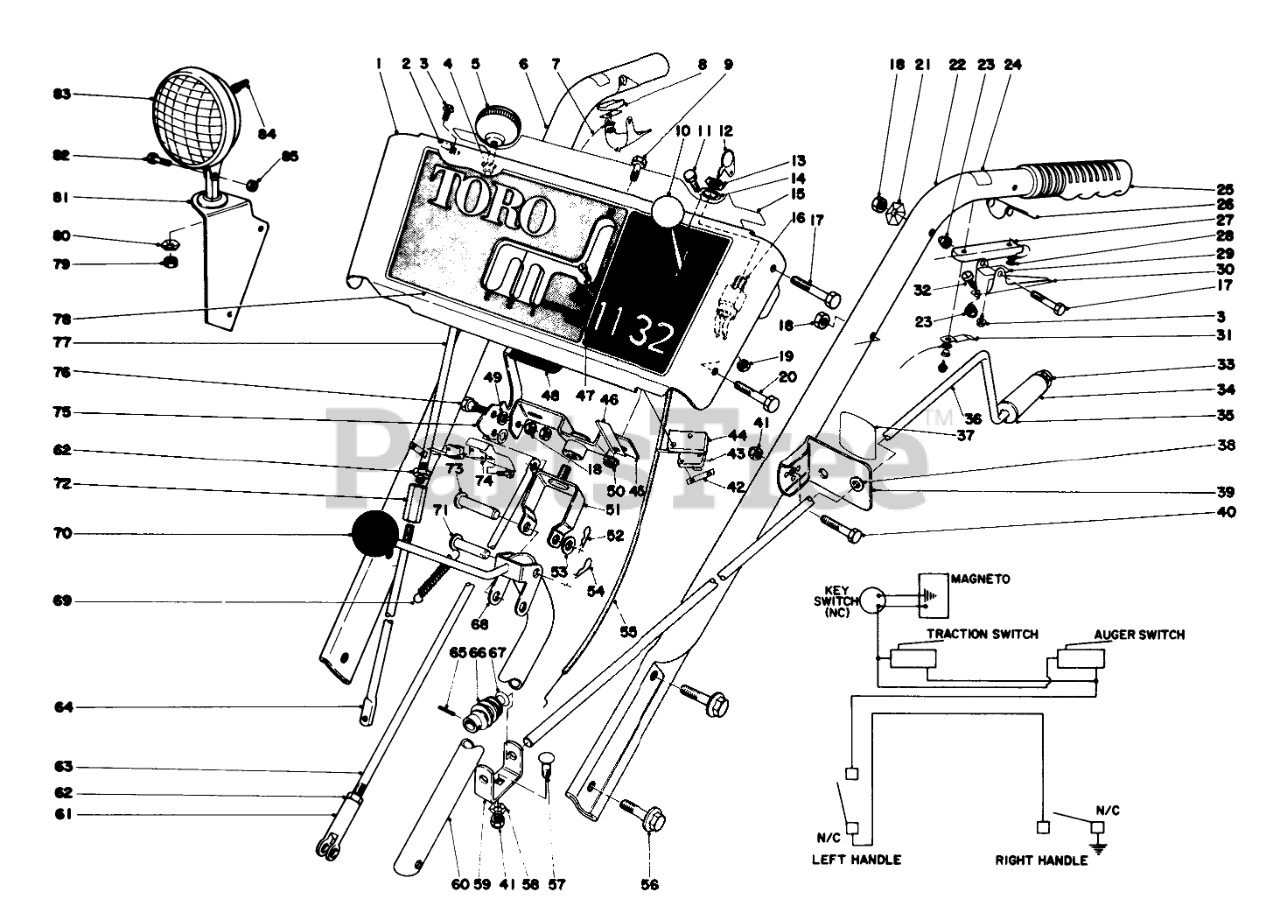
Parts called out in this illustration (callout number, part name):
1	Escutcheon Plate (Incl. Ref. #15 & 78)(Model 38160)
2	PLASTIC CLIP
3	SCREW
4	NYLINER #6LI-FF TYPE 7
5	KNOB-LEVER
6	Handle Right
7	WIRE HARNESS
8	Insulator
9	SCREW-HH
10	CONTROL KNOB
11	HEX HEAD SEMS 10-24X1/2
12	Key
13	NUT-HH
14	WASHER-TOOTH, INTERNAL
15	BACK ESCUTCH DECAL
16	SWITCH-ON / OFF
17	SCREW-HH
18	NUT-LOCK, CONE
19	Nut
20	SCREW-HH
21	Washer
22	LEFT HANDLE
23	NUT-CAP
24	INTERLOCK DECAL
25	Handle Grip
26	INTERLOCK SPRING
27	DUAL BRKT INSULATOR
28	WASHER INSULATOR
29	INTERLOCK CONTACT
30	SAFETY INTRLOCK LEVER
31	CONTACT BRACKET
32	NYLON SCREW 1/4 20
33	RETAINER-PUSH ON
34	CHUTE CONTROL GRIP
35	WASHER-FLAT
36	ROD CHUTE CONTROL
37	CHUTE DECAL
38	Bushing
39	Bracket Chute Control Mounting (Incl. Ref. #37 & 38)
40	SCREW-HH
41	NUT-LOCK, NI
42	NUT-SPEED
43	MICRO SWITCH
44	SWITCH MTG PAD
45	SWIVEL BLOCK WA
46	Retainer Wire
47	SCREW-SPH
48	AUGER CLUTCH HND GRIP
49	WASHER-PLAIN
50	NUT-LOCK, HHF
51	PIVOT BRKT WA
52	PIN-HAIR
53	WASHER-FLAT
54	PIN-COTTER
55	Throttle Contrl
56	SCREW-HHF
57	BOLT-CARR
58	WASHER-LOCK
59	WORM BRACKET
60	Rod Traction Shift
61	CLEVIS
62	NUT-HJ
63	DRAG LINK
64	LOWER WHL CLUTCH ROD
65	PIN-SPRING
66	GEAR-WORM, CHUTE
67	WASHER-SPRING
68	SHIFT ROD WA
69	CONT ROD SPRING 0
71	PIN-CLEVIS
72	WHL ROD COUPLING
73	PIN-CLEVIS
74	SWITCH BRKT
75	Auger Clutch Handle
76	SCREW-SHOULDER
77	UP WHEEL CLUTCH ROD
78	ESCUTCHEON DECAL
79	NUT-HEX
80	LOCKWASHER-PYRAMID
81	Lamp Mount
82	SCREW-HH
83	HEADLAMP ASM
84	BOOT-SWITCH
85	NUT-HEX, SIDE DEFORM
